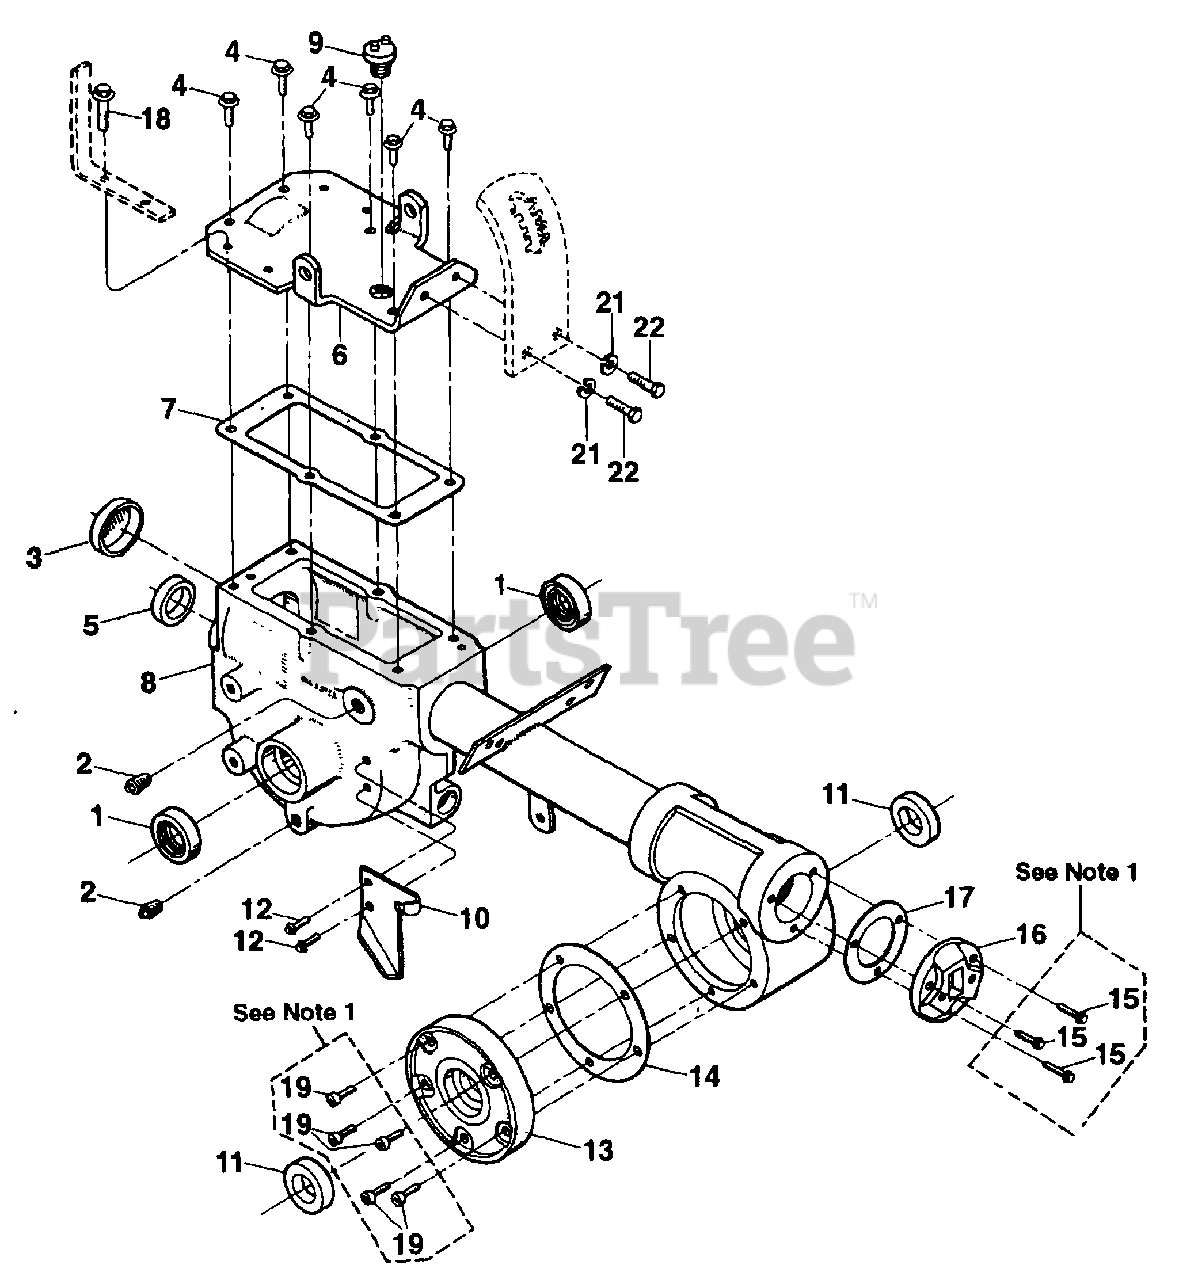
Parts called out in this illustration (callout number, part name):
1	Oil Seal-double lip, wheel shaft, right and left sides
2	Plug-pipe, 1/4, oil level hole and gear oil drain hole
3	Seal-transmission bore
4	Screw-flanged hex hd., 5/16-18 x 3/4
5	Oil Seal-input pinion shaft
6	Cover-top of transmission
7	Gasket-transmission top cover
8	Transmission case, tube and rear housing assembly
9	Plug-gear oil fill hole
10	Plate-wheel drive cable mounting
11	Oil Seal-tiller shaft, left and right sides
12	Screw-flanged hex hd., 5/16-18 x 5/8
13	Cover-tiller housing, left side
14	Gasket-tiller housing cover, .010 (fits all covers)
15	Screw Kit
16	Cap-rear bearing
17	Gasket-rear bearing cap, .010 thick
18	Screw-flanged hex hd., 5/16-18 x 1
19	Screw Kit
21	Lockwasher-3/8
22	Screw-hex hd., 3/8-16 x 3/4
